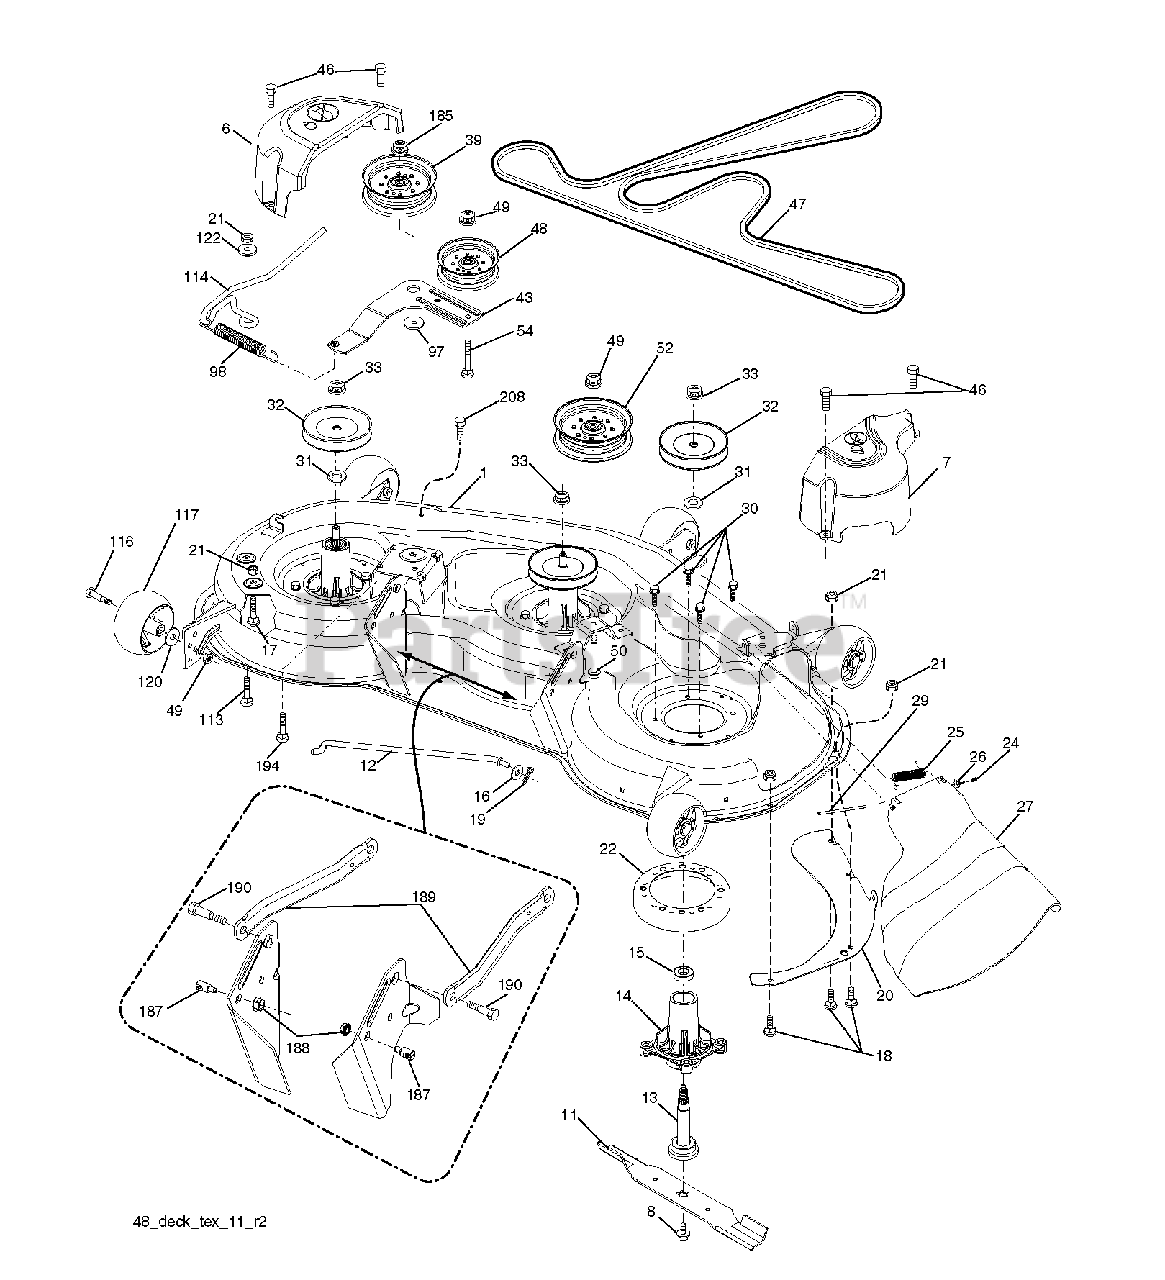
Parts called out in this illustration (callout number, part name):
1	DECK.WELDMENT.48"2006
6	COVER.MANDREL.LH.48"
7	COVER.MANDREL.RH.48"
8	BOLT.WASHER.ASM.7/16-2
11	48" HI-LIFT BLADE
12	ROD.ANTI.SWAY.48/54"K4
13	SHAFT ASM MANDREL
14	HOUSING MANDREL
16	WASHER
17	BOLT
18	BOLT
19	PIN.COTTER.5/16.BOW TI
20	BAFFLE, VORTEX MWR
21	LOCKNUT
22	STRIPPER, MWR ROUND
24	CAP-SLEEVE LT
25	SPRING, TORSION
26	NUT PUSH M
27	DEFLECTOR SUBS TO 532 180655
29	ROD.HINGE
30	SCREW, WASHER HEAD
31	WASHER.SPACER.MANDREL
32	PULLEY MANDREL
33	NUT.FLANGE.LOCK.TOP
39	PULLEY.IDLER.4.50/HUB SPECIAL
43	ARM.IDLER
46	SCREW.1/4-20X5/8
47	BELT.DRIVE.DECK
48	PULLEY.IDLER.48"PRIMARY
49	NUT LOCK FLG 3/8-16 UNC
50	SCREW TT 3/8-16X2-1/4 UNC
52	PULLEY.IDLER.2006
54	BOLT.3/8-16X1.50
98	SPRING, DECK DRIVE
114	ROD.TENSION.RELIEF.TEX
116	BOLT.SHOULDER.3/8-16X3-5/8
117	WHEEL. GUAGE RALLY
122	BUSHING.RELIEF.TENSION
185	NUT.LOCK.FLANGE.7/16
187	STUD.FASTNER.W/ANTI-ROTATE
188	NUT LOCK HEX FLANGE 5/16-18
189	ARM.SUSPENSION.MOWER
190	BOLT.SHOULDER
194	BOLT.CARR.SQNK.7/16
208	SCREW 3/8-16X1/2
